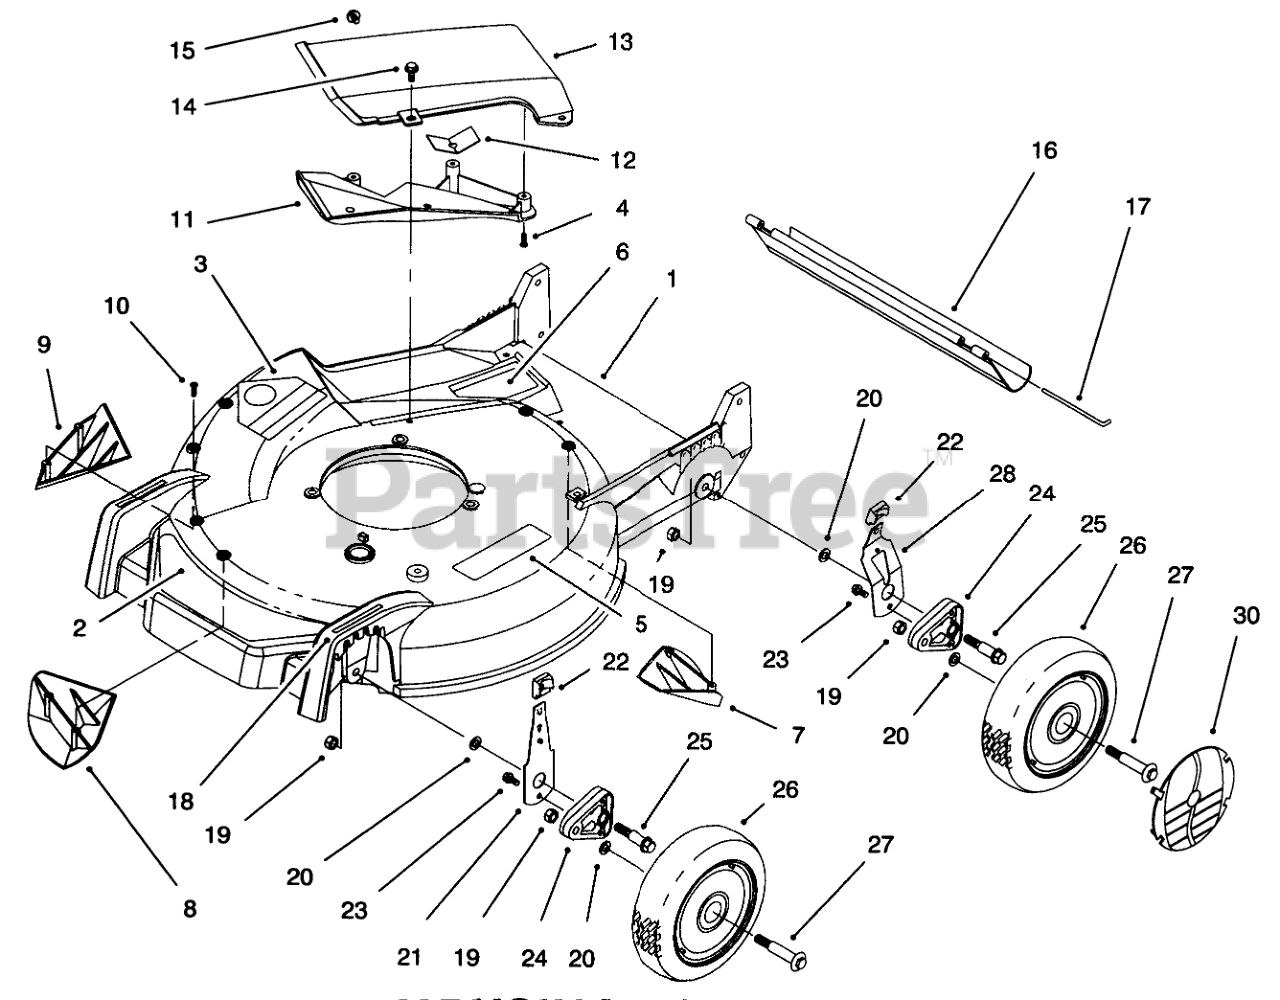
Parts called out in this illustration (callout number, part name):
1	Housing-21" (Incl. Ref. #3, 5, & 6)
2	DECAL - DECK
3	DECAL-DANGER
4	Screw-PPH
5	DECAL-WARNING
6	DECAL - DANGER
7	KICKER-REAR
8	KICKER-FRONT
9	KICKER-RH
10	SCREW-PPH
11	Deflector-Recycler
12	Guard-Cover
13	Cover-Recycler (Incl. Ref. #4, 11, & 12)
14	SCREW-HWH
15	SCREW AND WASHER ASM
16	SHIELD-TRAILING
17	ROD-SHIELD
18	DECAL - HOC
19	NUT-LOCK
20	WASHER
21	FRONT SPRING ARM ASM
22	KNOB-ARM
23	SCREW-HWH
24	ARM-PIVOT, FRONT
25	BOLT-SHOULDER
26	WHEEL AND TIRE ASM
27	BOLT-WHEEL
28	RH SPRING ARM ASM
30	WHEEL COVER
